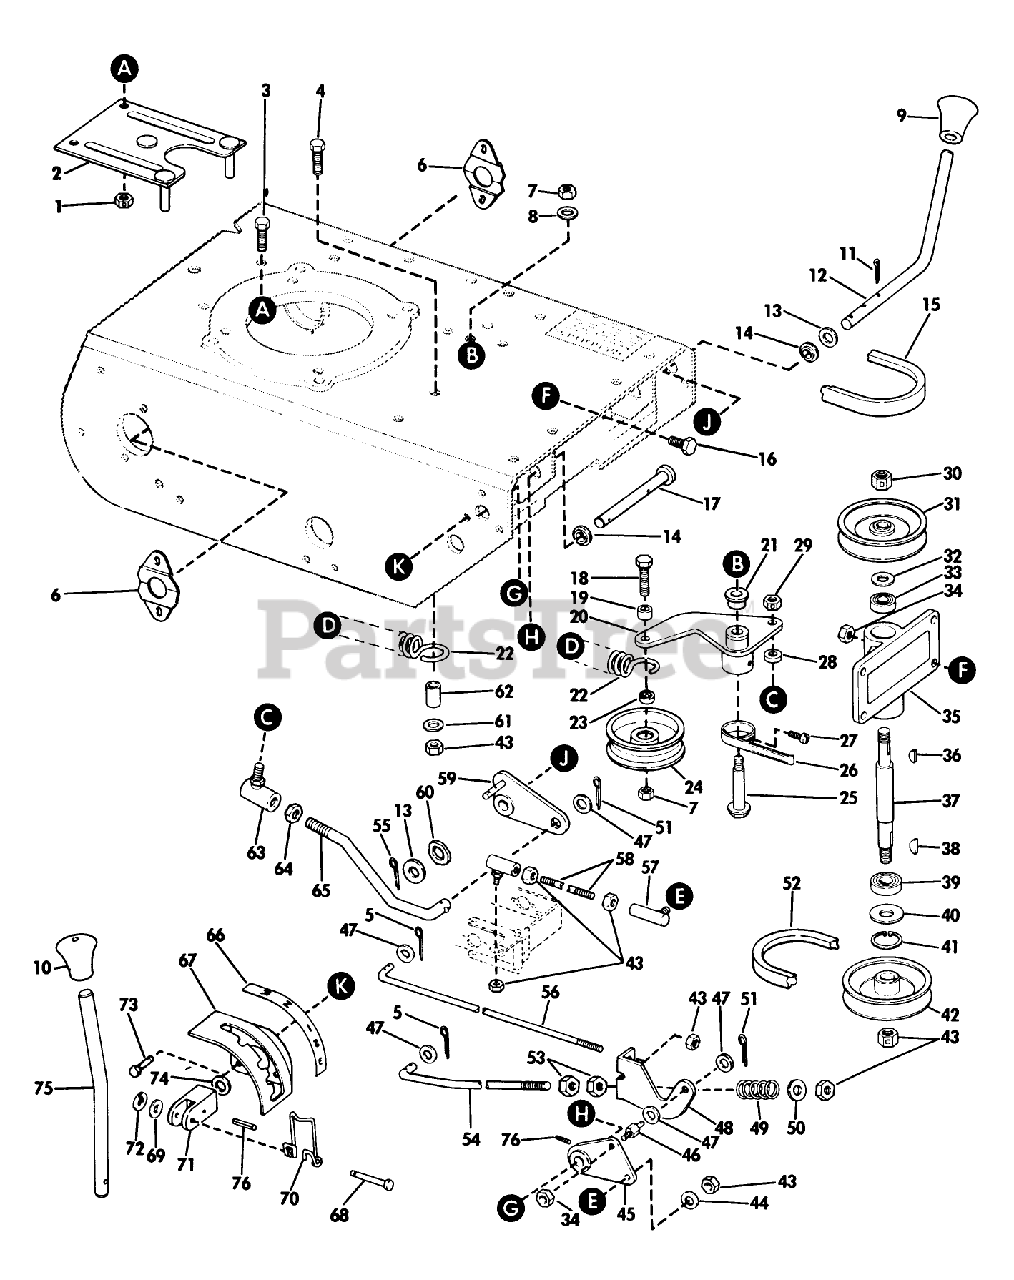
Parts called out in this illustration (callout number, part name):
7	LOCKNUT
12	Cotter Pin
43	STOP NUT
53	STOP NUT
55	Cotter Pin
